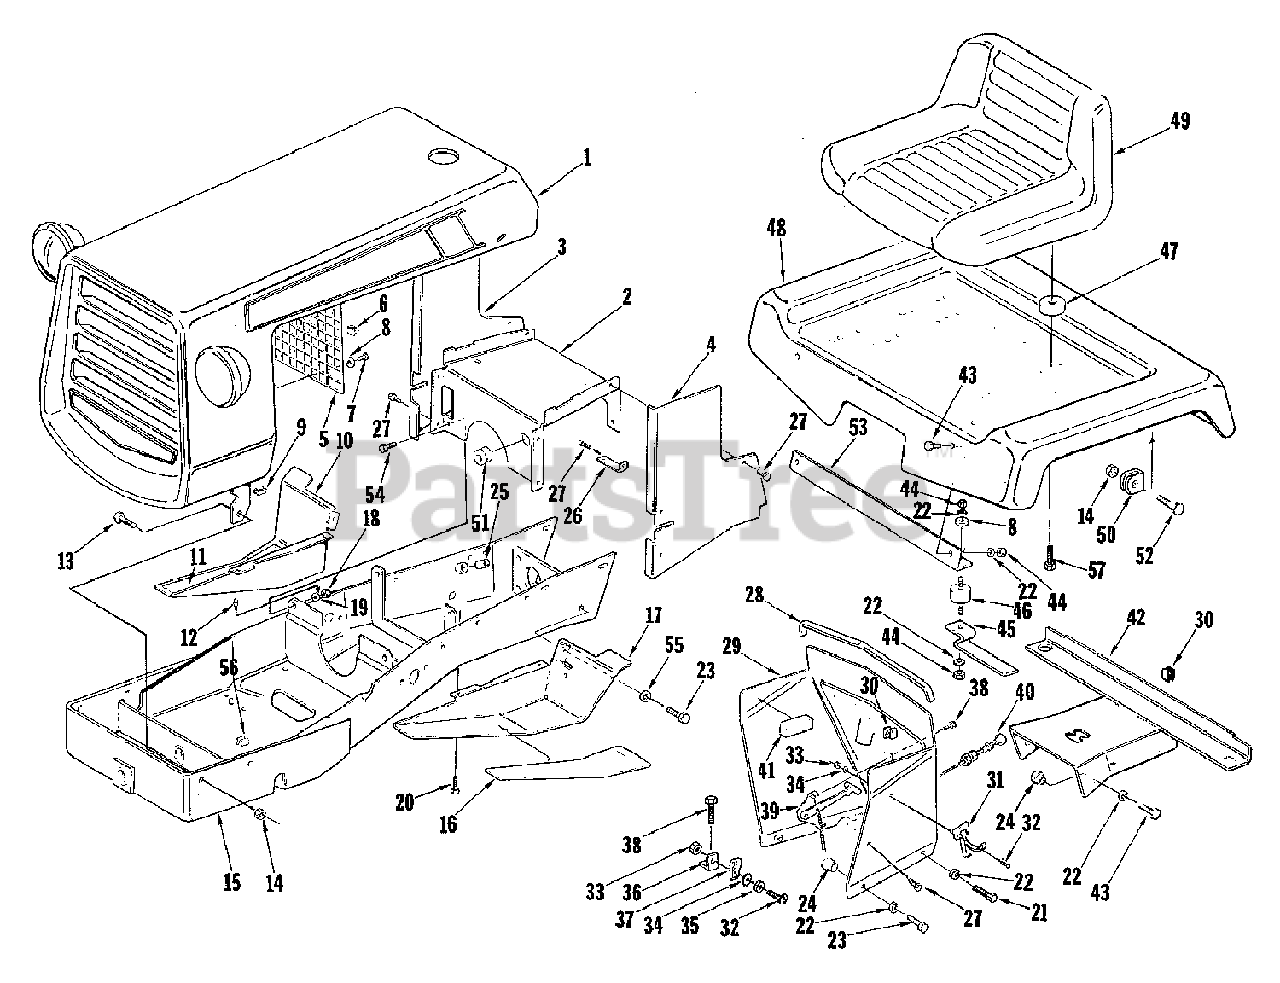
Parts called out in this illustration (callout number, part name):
1	HOOD ASSEMBLY
2	SUPPORT ASSEMBLY, Battery
3	PANEL, Side (R.H.)
4	PANEL, Side (L.H.)
5	SCREEN, Grille
10	FOOT REST (R.H.)
11	PAD, Foot (R.H.)
12	FITTING, Lube (Drive Type)
13	BOLT, Carriage, 3/8-16 x 3/4
14	NUT, Hex Lock, 3/8-16
15	FRAME ASSEMBLY
16	PAD, Foot (L.H.)
17	FOOT REST (L.H.)
18	NUT, Hex Head, 3/8-16
19	WASHER, Lock, 3/8
20	SCREW, Taptite, 3/8-16 x 3/4
21	SCREW, Lock, 5/16
22	WASHER, Lock, 5/16
23	SCREW, Hex Head Taptie, 3/8-16 x 1/2
24	NUT, Retainer, 5/16-18
25	BEARING, Sleeve
26	CLIP, Closed
26	CLIP, Closed (T-16H)
27	SCREW, Taptie, 1/4-20 x 1/2
28	BOULDING, Dash
29	PANEL ASSEMBLY, Instrument
32	SCREW, Round Head, 10-24 x 3/8
33	NUT, Hex, 10-24
34	WASHER, Lock, #10, Extension Tooth
36	BRACKET, Throttle Cable
37	CLIP, Throttle Cable
38	SCREW, Tapping, 1/4-20 x 5/8 (Taptite)
40	CHOKE (Includes Nut & Washer)
41	GASKET, Felt
42	COVER ASSEMBLY, Frame
43	SCREW, Hex Head Cap, 5/16-18 x 5/8
44	NUT, Hex, 5/16-18
45	CLIP, Spring
46	CONNECTOR, Cushion
47	CONNECTOR, Cushion
48	DECK ASSEMBLY, Seat
50	STOP, Seat Deck
51	GROMMET (T-10, T-16S)
51	GROMMET (T-16H)
52	SCREW, Hex Head Cap, 3/8-16 x 1-1/4
53	BRACKET, Front Seat Deck
54	SCREW, Hex Cap, 3/8-16 x 3/4
55	WASHER, Flat, 13/32
57	SCREW, Cap, 5/16-18 x 1
